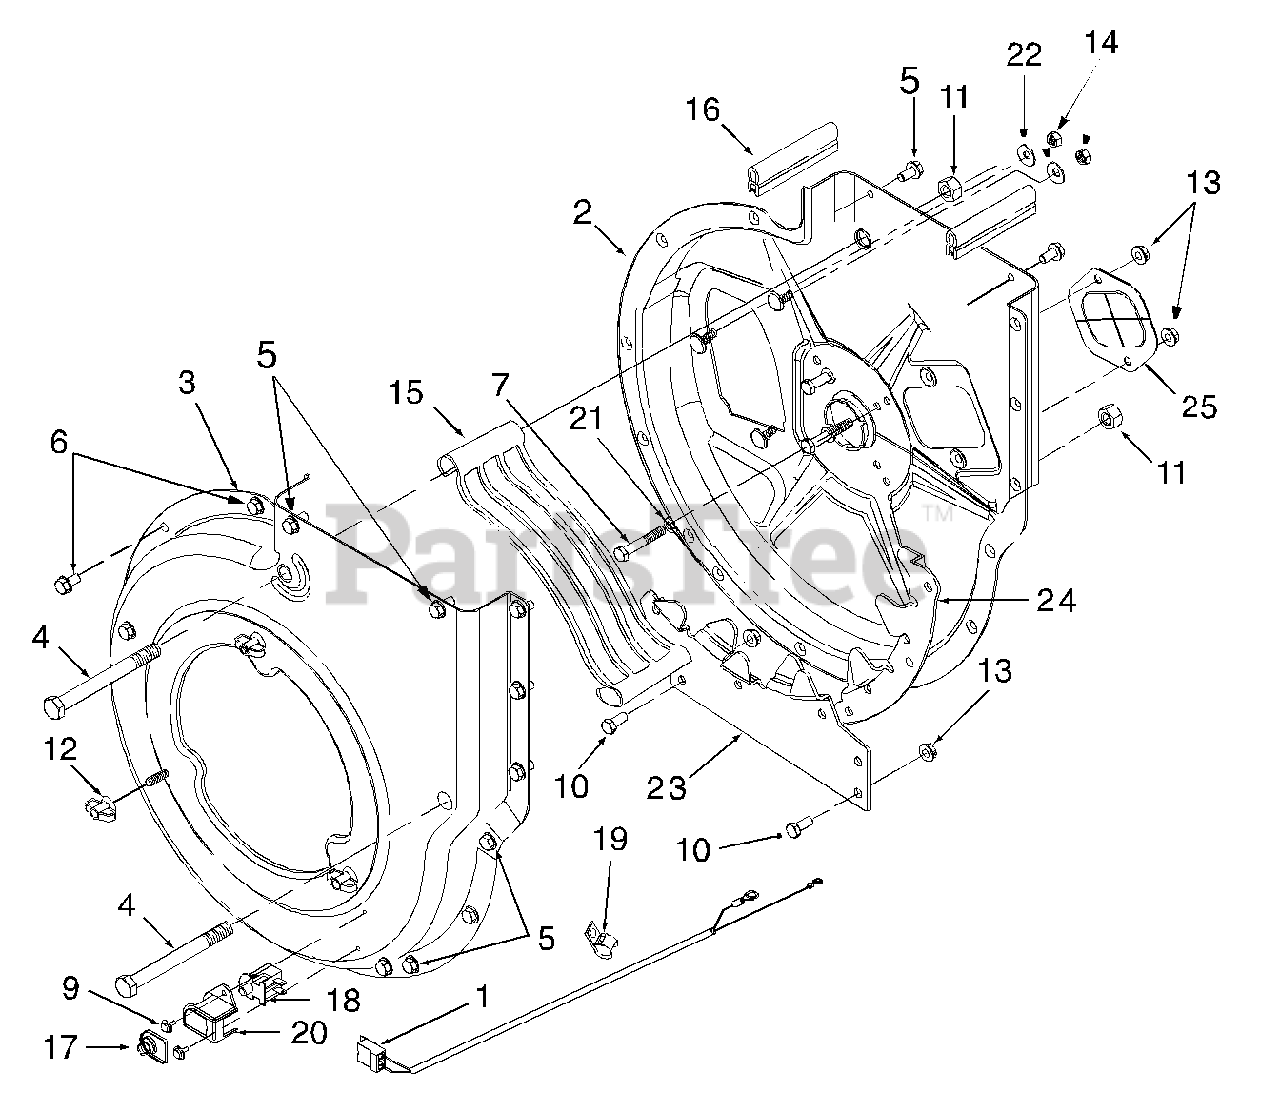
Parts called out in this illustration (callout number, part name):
1	Harness, Wire
2	Housing Ass'y, Inner Flail
3	Housing Ass'y, Outer Flail
4	Screw, Hex Cap, 1/2-13 x 5.0
5	Screw, Hex Wash Hd Tapp 5/16-18 x .62
6	Screw, Hex Wash Hd Tapp 5/16-18 x .50
7	Screw, Hex Cap, 5/16-24 x 2 GR5
9	Screw, Hex Wash Hd Tapp #10-16 x 3.8
10	Screw, Hex Cap, 5/16-18 x .75 GR5
11	Nut, Hex Center Lock, 1/2-13
12	Knob, 5/16-18
13	Nut, Hex Flange Lock, 5/16-18
14	Nut, Hex, 5/16-18
15	Screen, Discharge
16	Rubber Seal
17	Cover, Switch
18	Switch, Snap Mount
20	Cover, Safety Switch Mounting
21	Washer, Lock 5/16
22	Washer, Bell .345 x .88 x .06
